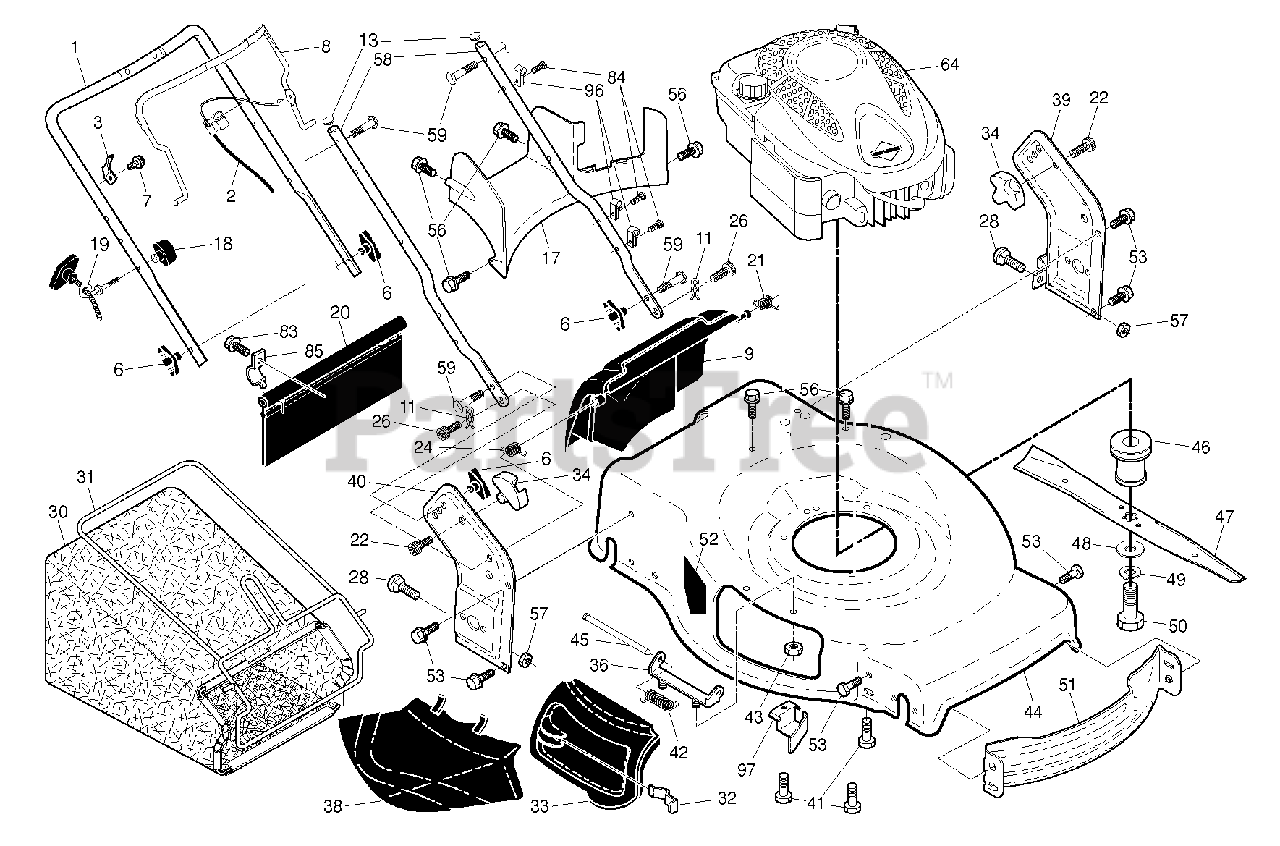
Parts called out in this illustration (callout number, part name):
1	HANDLE.UP.DSTR.EZ.FG/RGD.CREAS
2	CABLE.MZR.ZONE.CONTROL
3	BRACKET.UPSTOP.RT
8	BAIL.MZR.EZ2.DSTRT.22+.421
9	DOOR.REAR.22+GEN.RG.EBA.BLK
11	COTTER.HAIRPIN.DOOR/HANDLE.PIV
13	PLUG.PLASTIC.7/8".14-20.GAUGE
17	BAFFLE.REAR.22+RGD.AWD.PLASTIC
18	T-KNOB.NEW ROPE GUIDE
19	Rope Guide, Blk Zinc Chrom
20	SKIRT.REAR.22PLUS.RGD.LW.2012
21	SPRING.LH.GRAY
22	SCREW.PAN.HEAD.#10
24	SPRING.RH.GRAY
26	SCREW,DOOR/HANDLE.PIVOT
28	Carriage Bolt, 5/16-18 X 5/8
30	GBAG.A1640416S.BLK.PPRO.MRG.
31	Grass Bag Frame, 22+ Black
32	LATCH.DOOR.ZINC
33	DOOR.MULCH.22.BLACK.MULTI-BRAN
34	BRACKET.GRASSBAG.ATTACHING.BLK
36	BRACKET.ASM.HINGE.21.FWGD.
38	DEFLECTOR.CLIPPING.22.BLACK
39	Handle Bracket Assembly, LH 22+ Black
40	Handle Bracket Assembly, RH 22+ Black
41	BOLT 3/8-16X1-1/8
42	SPRING.TORSION
43	NUT.HEX.FLANGE.1/4
44	KIT.HSG.22+.RGD.MC.WO.BLK.TRI
45	ROD.HINGE.21
46	ADAPTER.BLADE.25MM.3MPH
47	BLADE.22+.PREMIUM/PREC.FGD/RGD
48	WASHER,HARDEN
50	SCREW, HEX HD 3/8-24 X 1-3/8
51	BAFFLE.FRONT.22.PLUS
52	No Step Decal
53	BOLT.5/16HEX.WHS.HD
56	SCREW.HX.13X.750
57	NUT.FLANGE.5/16
58	HANDLE.LOWER.22+BT.2PC.BLK
59	BOLT, HANDLE 5/16-18X1.75
83	TAPPING SCREW
84	FASTENER.PUSH.O.250X0.783
85	BRACKET.SKIRT.22+.BZP
96	CLIP.CABLE.BLK
97	BRACKET.BELT.GUIDE.22+.BZP
